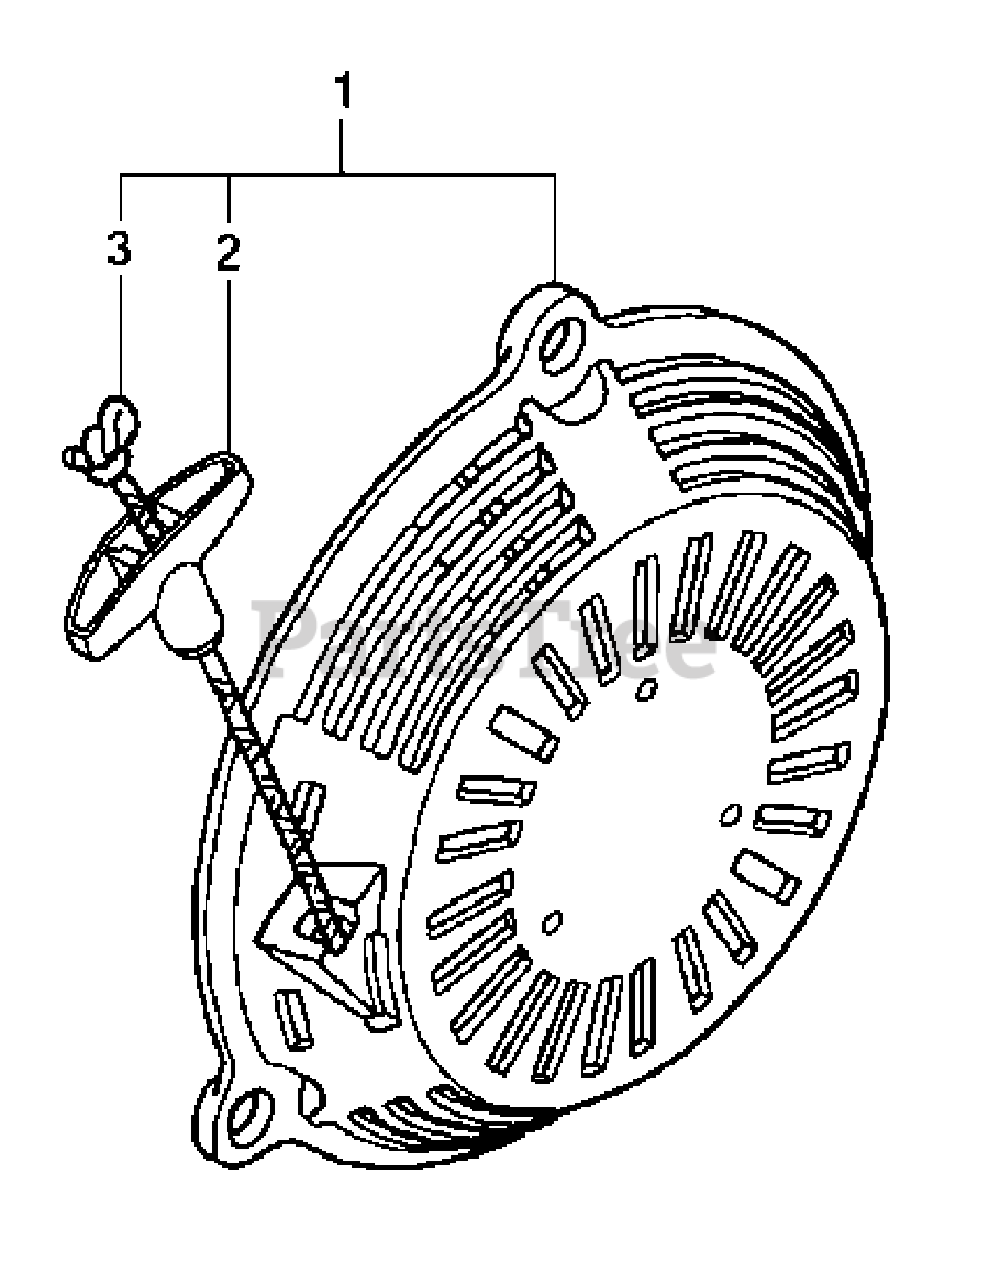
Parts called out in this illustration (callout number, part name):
1	Starter Assy., Recoil *Nh1 *
2	Grip, Starter
3	Rope, Recoil Starter
